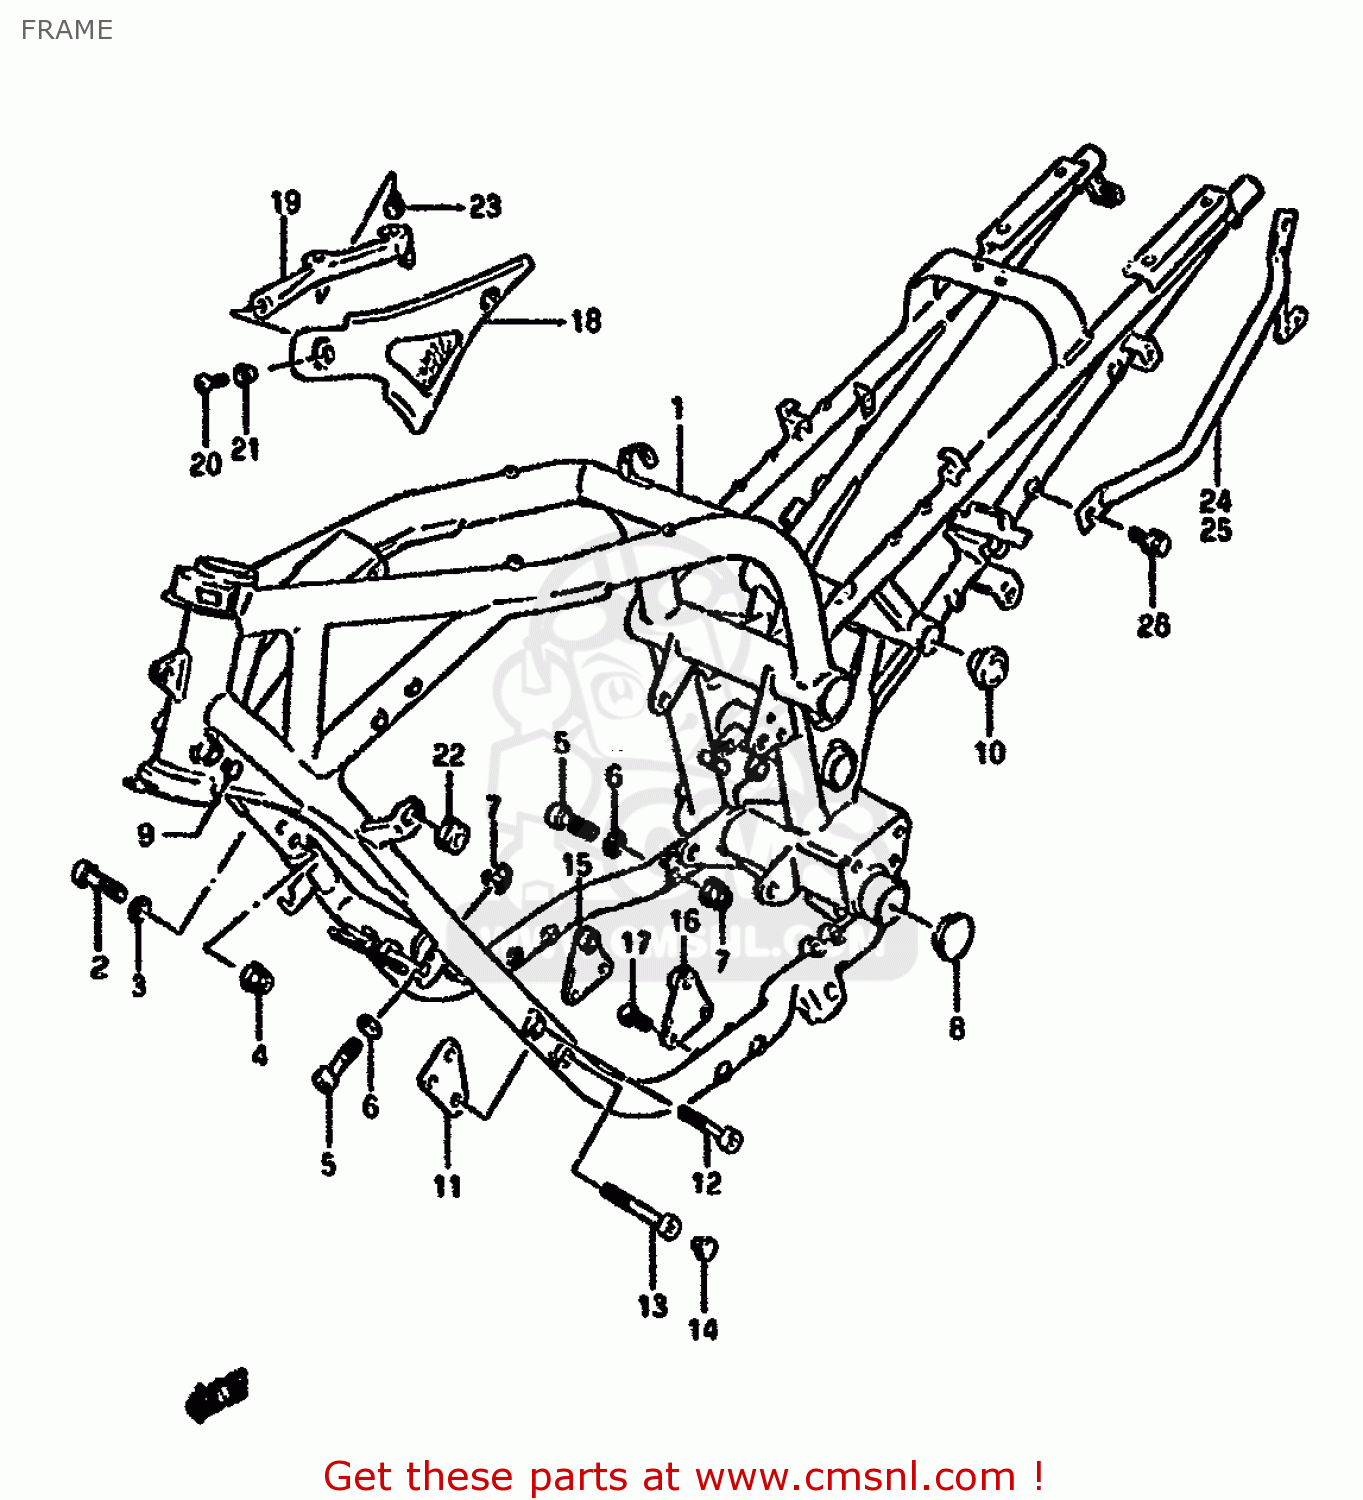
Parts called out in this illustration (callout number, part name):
1	FRAME SET (BLACK)
2	BOLT 10X38
3	WASHER
4	NUT 10MM
5	BOLT(10X33)
6	WASHER
7	NUT 10MM
8	CAP,BODY TUBE
9	CAP(OD:14)
10	CAP(OD:45)
11	PLATE,ENGINE MOUNTING NO.1
12	BOLT
13	BOLT
14	CAP(OD:12)
15	PLATE,NO.2 RH
16	PLATE,NO.2 LH
17	BOLT
18	COVER,FRAME HEAD,LEFT
19	PLATE,HEAD COVER,L
20	SCREW(5X14)
21	WASHER(5.2X14X1.5)
22	CUSHION
23	SCREW
24	GRIP,REAR RH
25	GRIP,RR,L
26	BOLT
